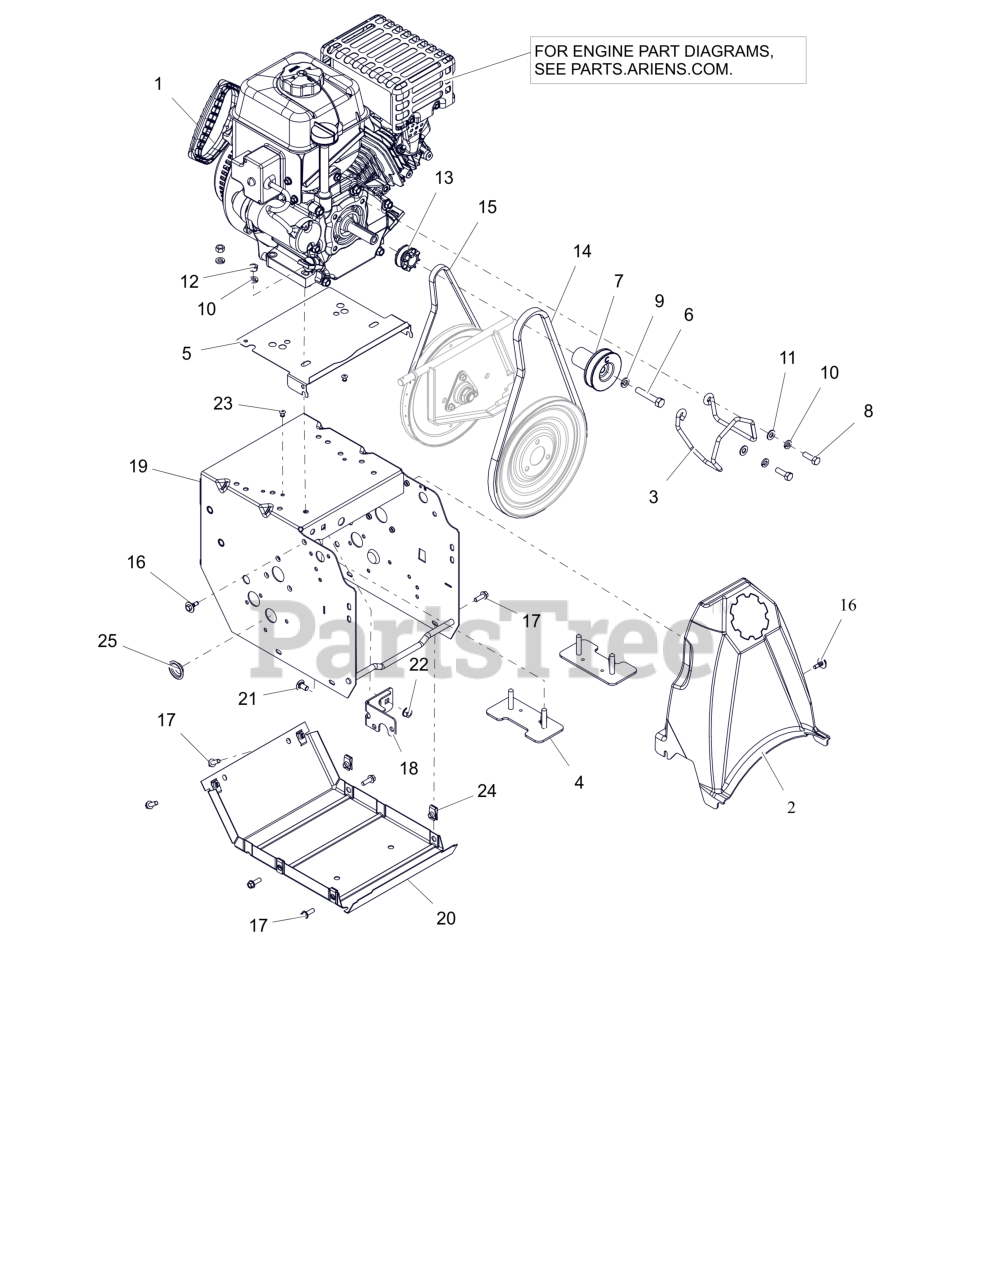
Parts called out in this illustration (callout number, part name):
1	ENGINE, AX223 GEN 2 120V
2	COVER- CLASSIC BELT
3	FINGER, BELT
4	STRAP, ENGINE BOLT-WELDMENT
5	BAFFLE, COMPACT
6	BLT, HEX .38-24X2.00 G5 ZCC
7	SHEAVE, ATTACHMENT SINGLE GRV
8	BLT, HEX 0.3125-24X1 G5 ZCC
9	WSHR,LK-REG .375X.094 ZCC
10	WSHR, LK-HVY .312X.097 ZCC
11	WSHR,FLT .344X.688X.065 ZCC
12	NUT, HEX .312-18 ZCC
13	SHEAVE, TRACTION
14	V-BELT, HA-RAW EDGE
15	V-BELT, 3L-WRAPPED
16	SCR-TAP .25-20X.5 CAPTIVE
17	BLT, HWH .25-20X.75 G5 ZCC
18	WELDMENT, FRAME BRACKET
19	FRAME, MAIN
20	COVER, BOTTOM
21	BLT, RHSSN .31-18X.625 G5 ZCC
22	NUT-LK-TOP-FLG .312-18 GF ZCC
23	RVT, POP .1875 ZCC
24	NUT-RTNR .25-20X.56
25	PLUG, HOLE - 1.00" FLEXTEMP
